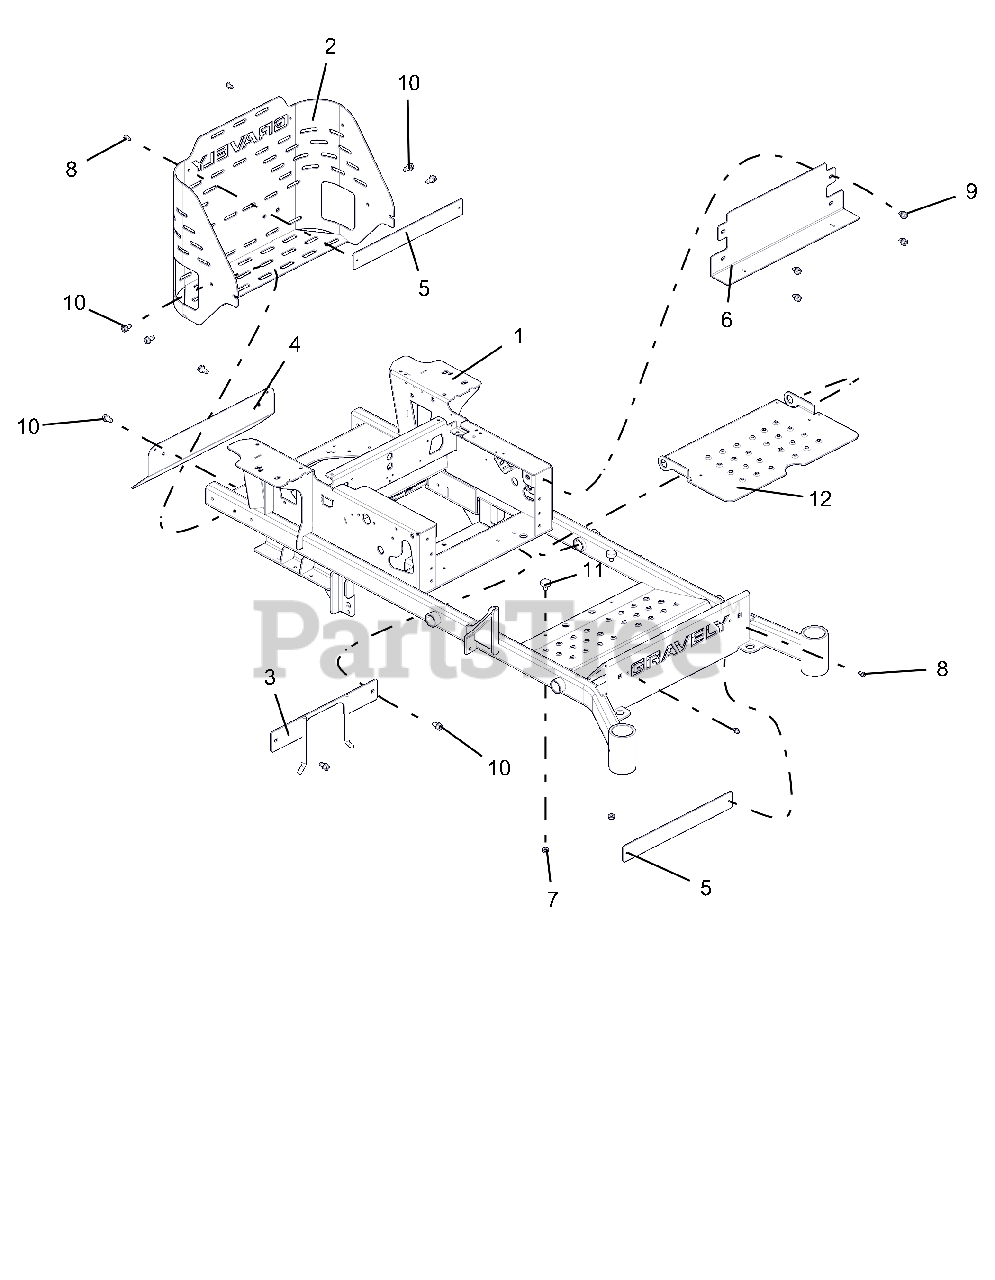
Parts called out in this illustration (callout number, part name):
1	48-52" MAIN FRAME W/SAFETY DECALS
2	REAR BUMPER W/SAFETY DECALS
3	WLDMT, PTO BELT FINGER-BLACK
4	SHIELD, MUFFLER HEAT
5	PLATE, BUMPER 2.00 x 16.50 - BLK
6	PLATE, PT/PT100 KICK-RED
7	@NUT-SPNLK-FLG .312-18 YWZC
8	SCR-TAP .25-20X.50 HWH TR YWZ
9	SCR-TAP .38-16X.50 HWH TR YWZ
10	SCR-TAP .38-16X.75 HWH TR YWZ
11	BUMPER, RUBBER
12	FOOT, PLATE W/SAFETY DECALS
